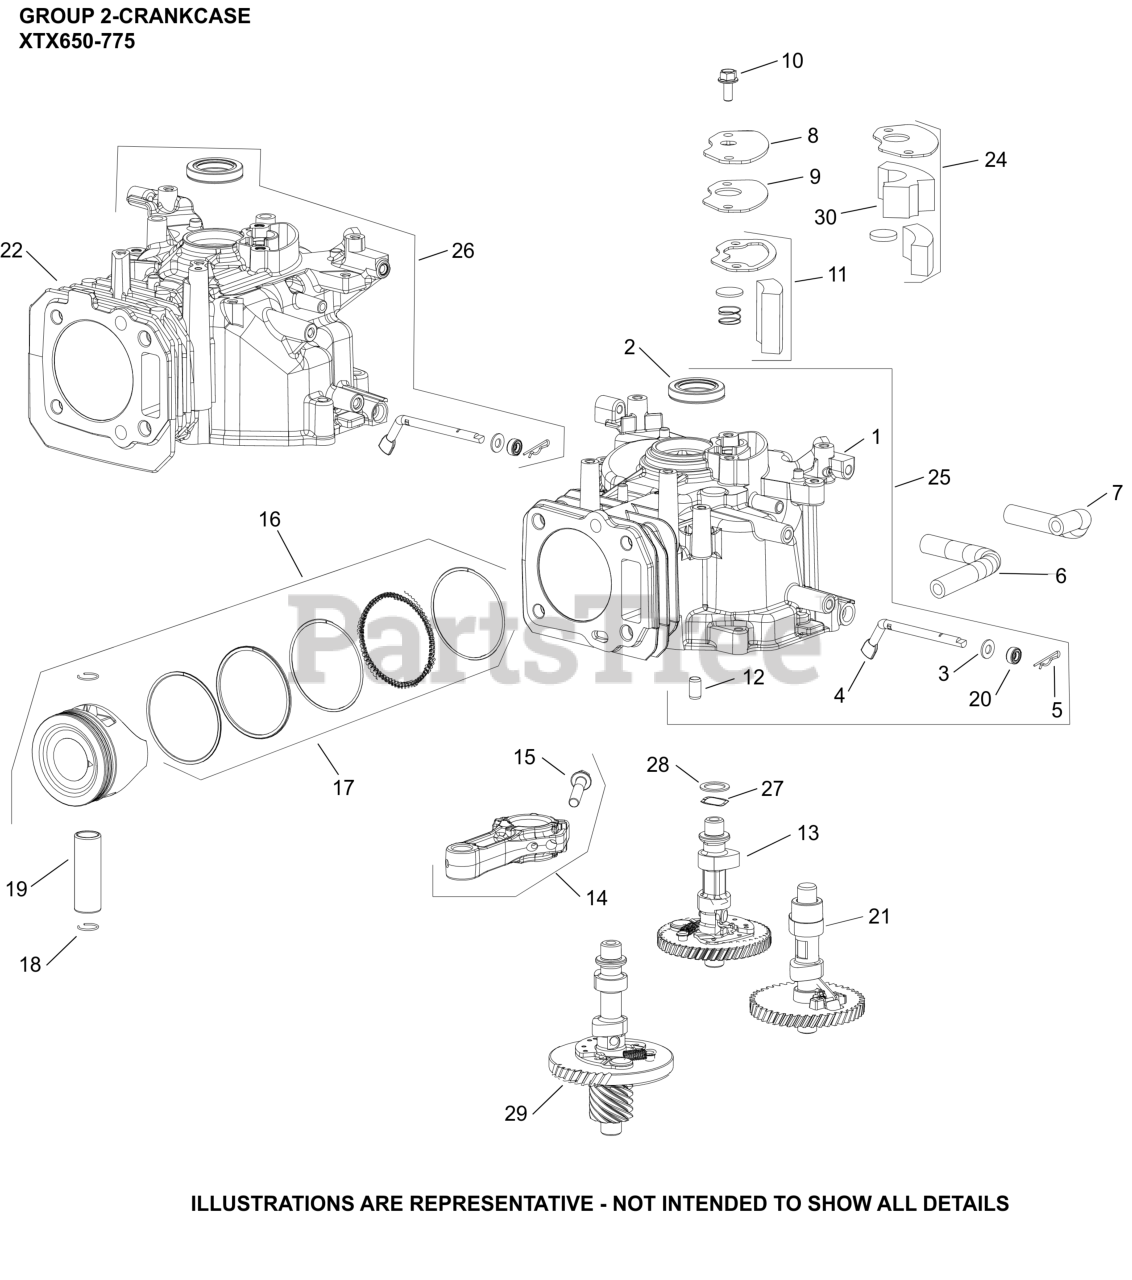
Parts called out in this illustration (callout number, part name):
2	SEAL, CCASE/FLYWHEEL
3	WASHER, FLAT (DIA 13mm O.D.)
5	CLIP, GOVERNOR SHAFT
6	HOSE, BREATHER
8	COVER, BREATHER
9	GASKET, BREATHER COVER
10	SCREW, HEX FLANGE (M6)-USE 25 086 433-S
11	KIT, BREATHER FILTER
14	ROD, CONNECTING ASSEMBLY
15	SCREW, HEX FLANGE (M7)
16	PISTON ASSEMBLY (SERVICE)
17	RING SET (SERVICE) (XT149)
18	RETAINER, PISTON PIN
21	CAMSHAFT, ASSEMBLY
24	KIT, BREATHER FILTER
25	KIT, CRANKCASE
30	FILTER, BREATHER MEDIA-USE 14 050 31-S
